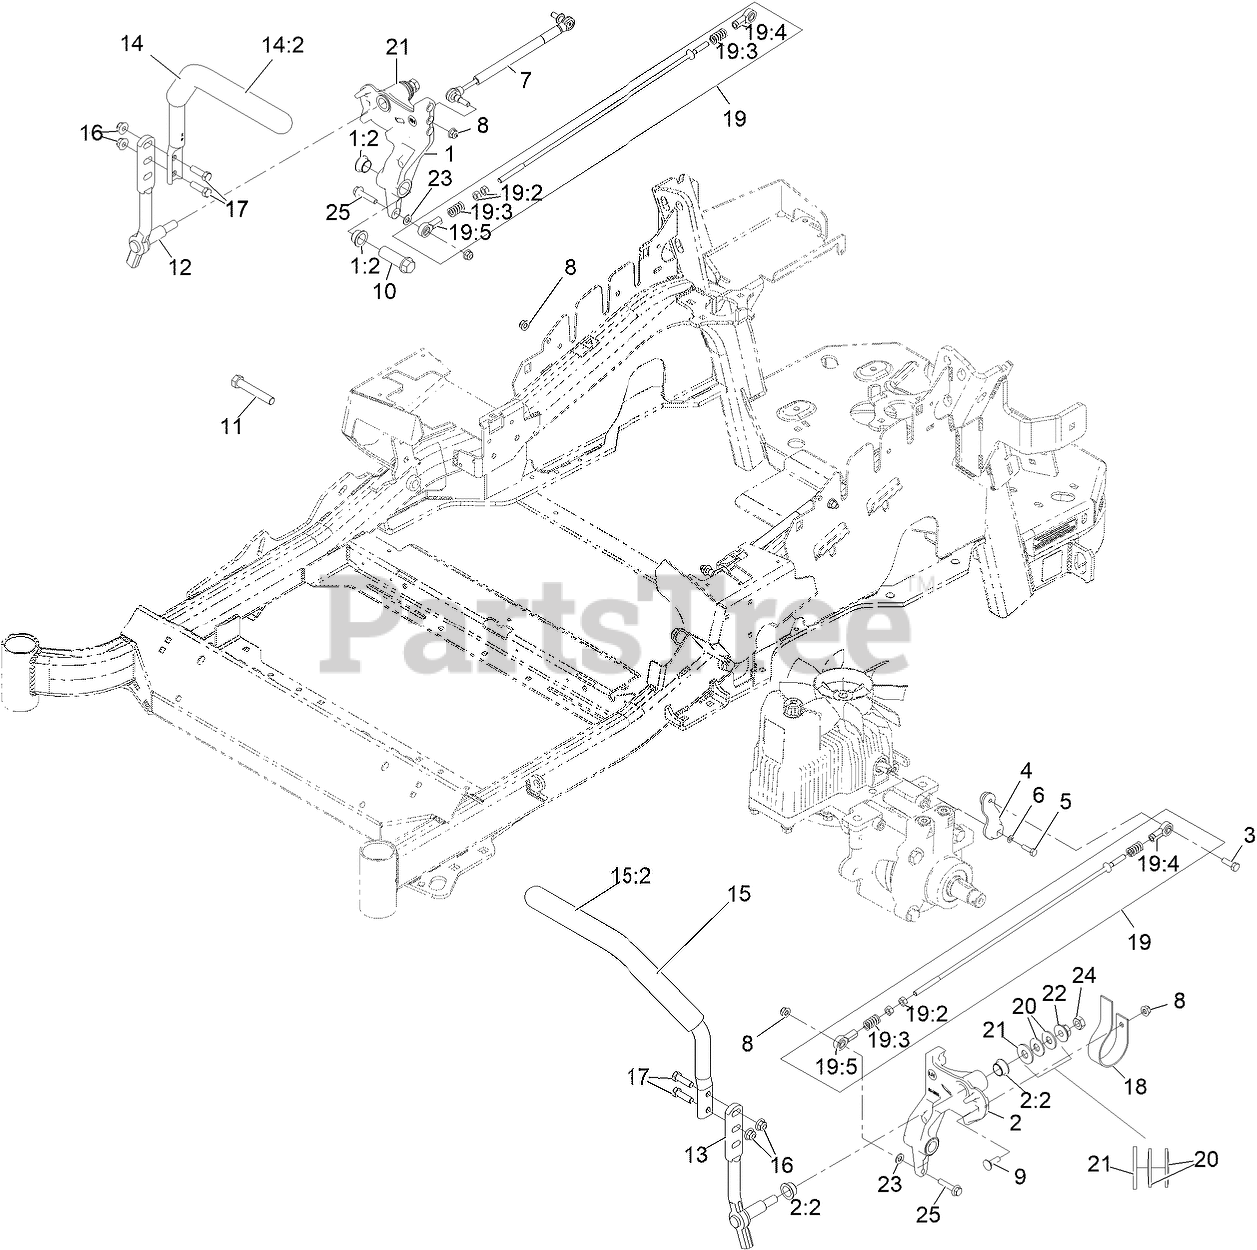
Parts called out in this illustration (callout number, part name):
1	RH MOTION CONTROL AND BUSHING ASM
1:2	BUSHING-FLANGE
2	LH MOTION CONTROL AND BUSHING ASM
2:2	BUSHING-FLANGE
3	SCREW-HH, THREAD LOCKING
4	ARM-CONTROL, PUMP
5	SCREW-HH
6	WASHER-SPRING
7	DAMPER-CONTROL, MOTION
8	NUT-HF, NI
9	BOLT-CARR
10	HUB-THREADED
11	SCREW-HH
12	LEVER-CONTROL MOTION, RH
13	LEVER-CONTROL MOTION, LH
14	RH HANDLE ASM
14:2	GRIP-LEVER, CONTROL
15	LH HANDLE ASM
15:2	GRIP-LEVER, CONTROL
16	NUT-HF, NI
17	SCREW-HH
18	SPRING-LEAF
19	PUMP LINKAGE REAR ASM
19:2	NUT-HEX
19:3	SPRING-COMPRESSION
19:4	BALLJOINT-LH
19:5	BALLJOINT-RH
20	WASHER-SPRING
21	WASHER-FLAT
23	WASHER-PLAIN
24	NUT-JAM
25	SCREW-HHF
